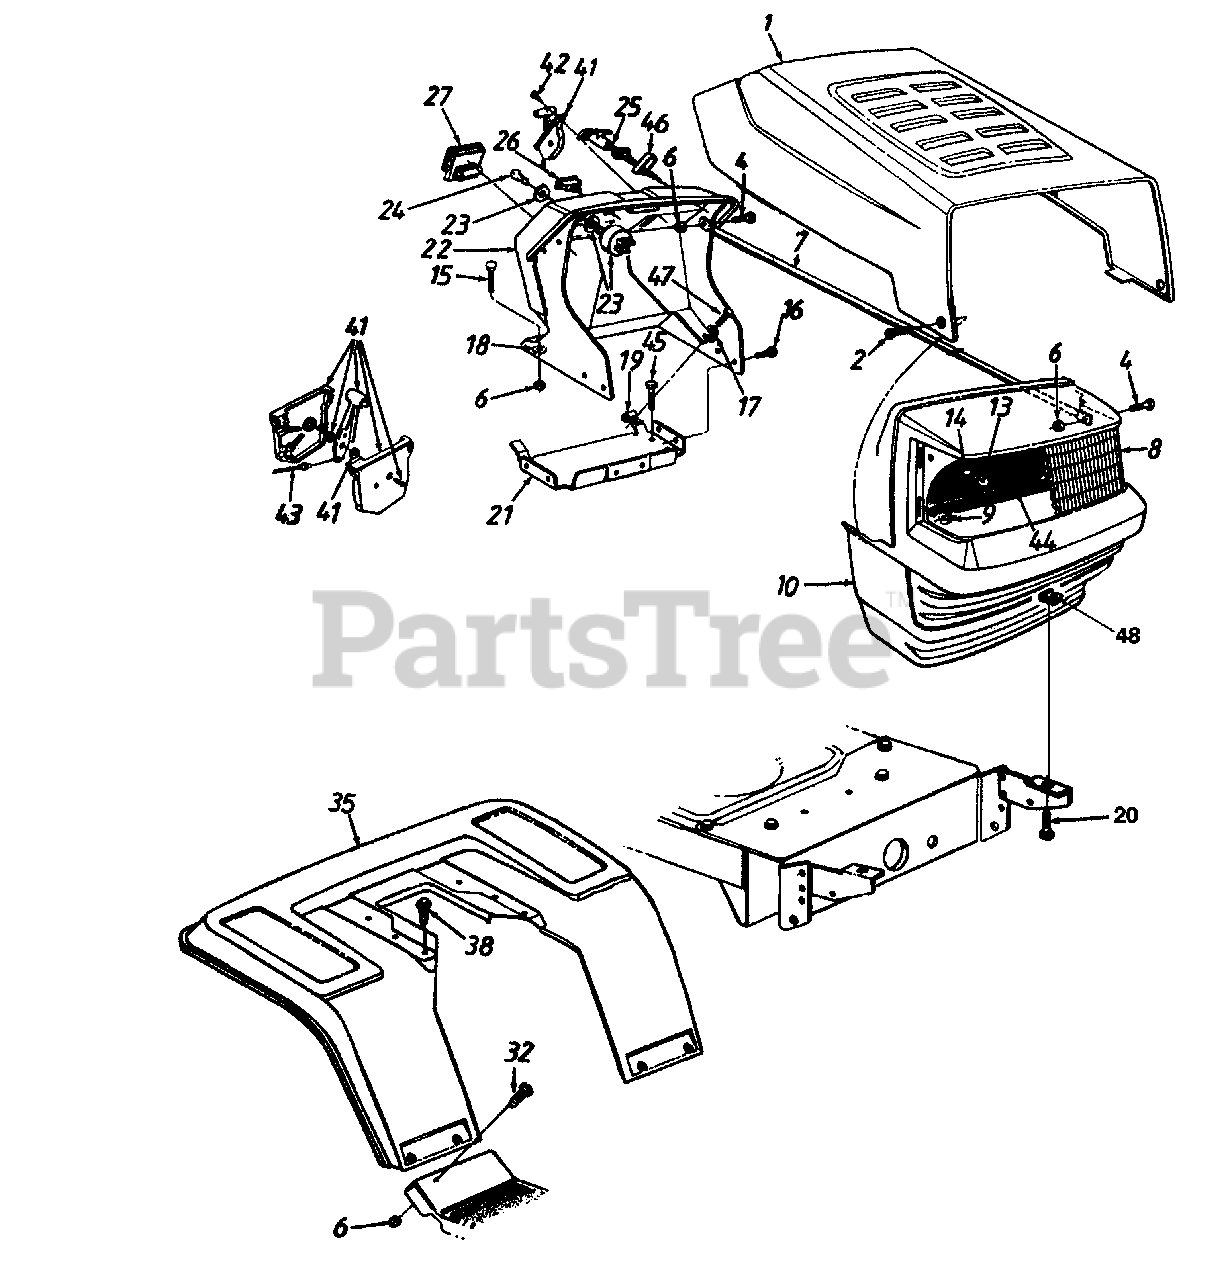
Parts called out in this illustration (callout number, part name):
4	Hex Bolt 1/4-20 x .62" Lg.
6	Hex Sems Nut 1/4-20 Thd.
8	Headlight Lens w/o Logo
9	Flange L-Nut 1/4-20 Thd.
10	Grille
13	Lamp
14	Socket
15	Carriage Bolt 1/4-20 x .75" Lg.
16	Hex Wash. Hd. TT-Tap Scr. 1/4-20 x .5" Lg.
17	Fl-Wash..281" I.D. x .73" O.D.
18	Bolt Retainer 1/4" I.D.
19	Speed Nut 1/4-20 Thd.
20	Hex Bolt 5/16-18 x .75" Lg.
23	Ignition Switch
24	Ignition Key
25	Choke Control 23" Lg.
26	Light Switch
27	Ammeter
32	Truss Mach. Scr. 1/4-20 x .5" Lg.
41	Throttle Box Ass'y.
42	Truss Mach. AB-Tap Scr. #10 x .5" Lg.
43	Throttle Control Wire 18.5" Lg.
44	Grille Reflector Label
45	Hex Wash. Hd. B-Tap Scr. 5/16-18 x .5" Lg.
46	Choke Retainer
47	Hex TT-Tap Scr. 1/4-20 x .75" Lg.
48	U-Nut 5/16-18 Thd.
